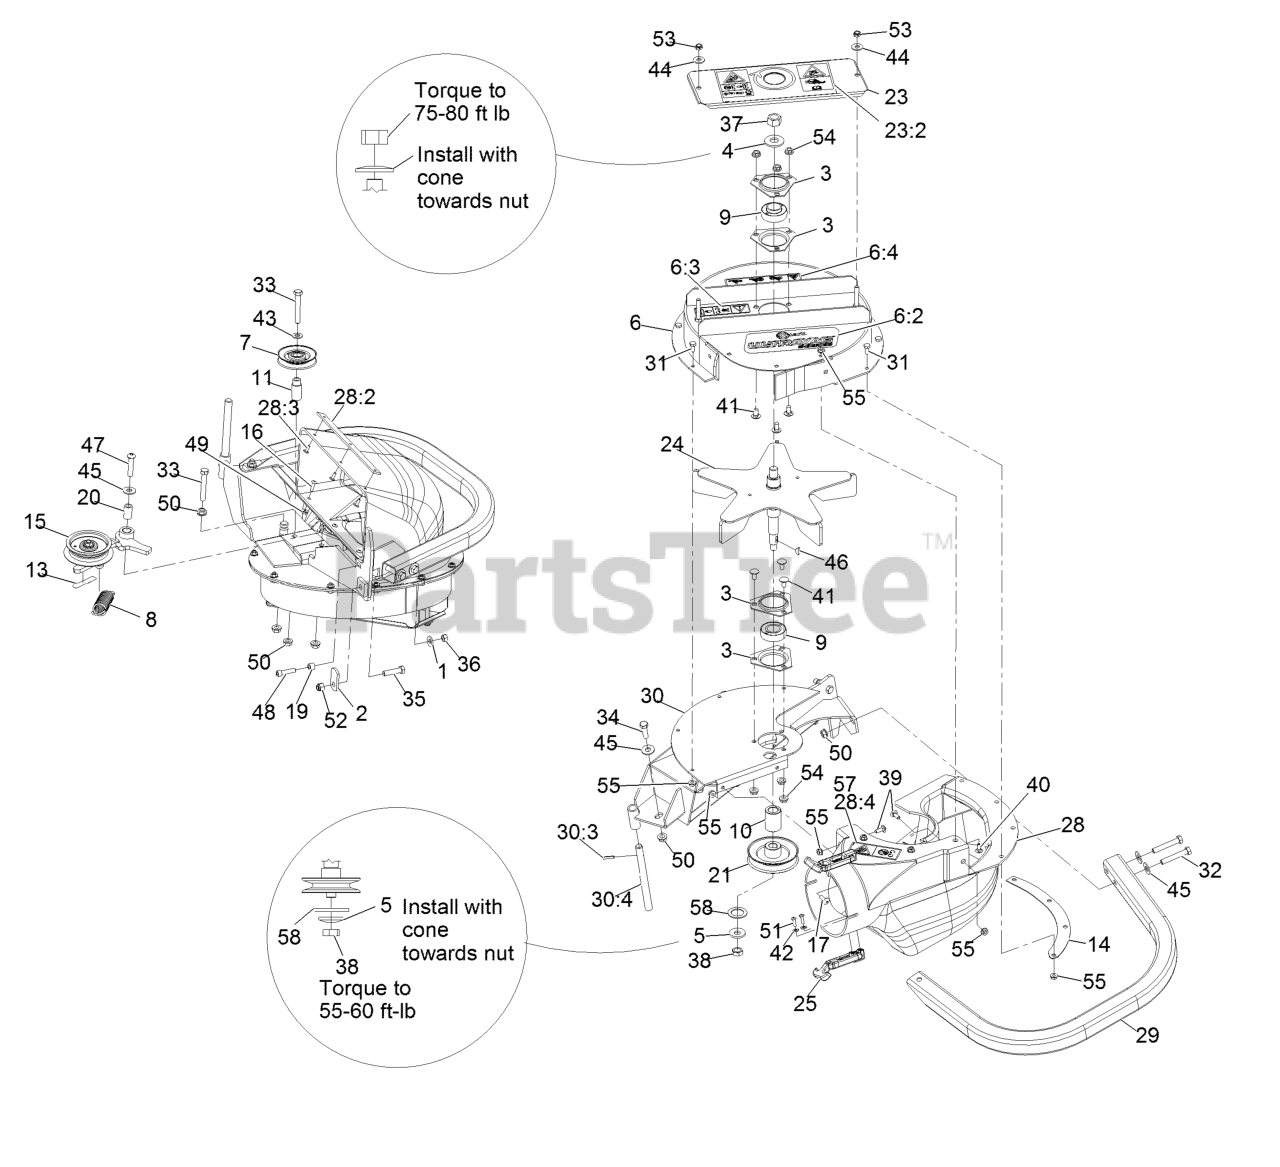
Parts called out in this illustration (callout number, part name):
1	Washer-Spring Disc 5/16
2	Latch-Catcher, Grass
3	Housing-Flange
4	Washer-Spring Disc 5/8
5	Washer-Spring Disc 1/2
6	ASM-Upper Housing Small
6:2	Decal-Ultravac S-Series
6:3	Decal-Missing, Cover
6:4	Decal-Warning Weight
7	Idler-Inside
9	Bearing
13	Decal-Warning
14	Plate-Backing, Blower
15	ASM, Idler
16	Screw-Truss Head #10-24 X 3/4
17	Screw-PPH 1/4-20 X 3/4
19	Bushing
20	Bushing-Pivot, Idler
21	Sheave-Blower
23	Cover, Bearing
23:2	Decal-Warning
24	Impeller
25	Latch-Rubber
28	Chute, Blower (46, 50 And 56)
28:2	Plate-Reinforcing
28:4	Decal-Warning
30	Weld, Frame Sm Blower
30:3	Rollpin 3/16 X 7/8
30:4	Shaft-Catcher, Grass
31	Screw-HH 1/4-20 X 5/8
32	Screw-HH 3/8-16 X 2 1/4
33	Screw-HH 3/8-16 X 2 1/2
34	Screw-HH 3/8-16 X 1 1/4
35	Screw-HH 3/8-16 X 1 1/2
36	Nut-Hex 5/16-18
37	Nut-Hex 5/8-18
38	Nut-Jam 1/2-20
39	Bolt-Carriage 1/4-20 X 3/4
40	Bolt-Carriage 1/4-20 X 5/8
41	Bolt-Carriage 5/16-18 X 5/8
42	Washer-#10 Std
43	Washer-3/8 SAE
44	Washer-5/16 Std
45	Washer-3/8 Std
46	Key-Woodruff 3/16 X 5/8
47	Screw-Button Head 3/8-16 X 1 3/4
48	Screw-Sh 5/16-18 X 1 1/4
49	Nut-Whizlock #10-24
50	Nut-Whizlock 3/8-16
51	Screw-PPH #10-24 X 5/8
52	Nut-Nyloc 3/8-16
53	Nut-Nyloc 5/16-18 Thin
54	Nut-Whizlock 5/16-18
55	Nut-Whizlock 1/4-20
57	Decal-Warning
